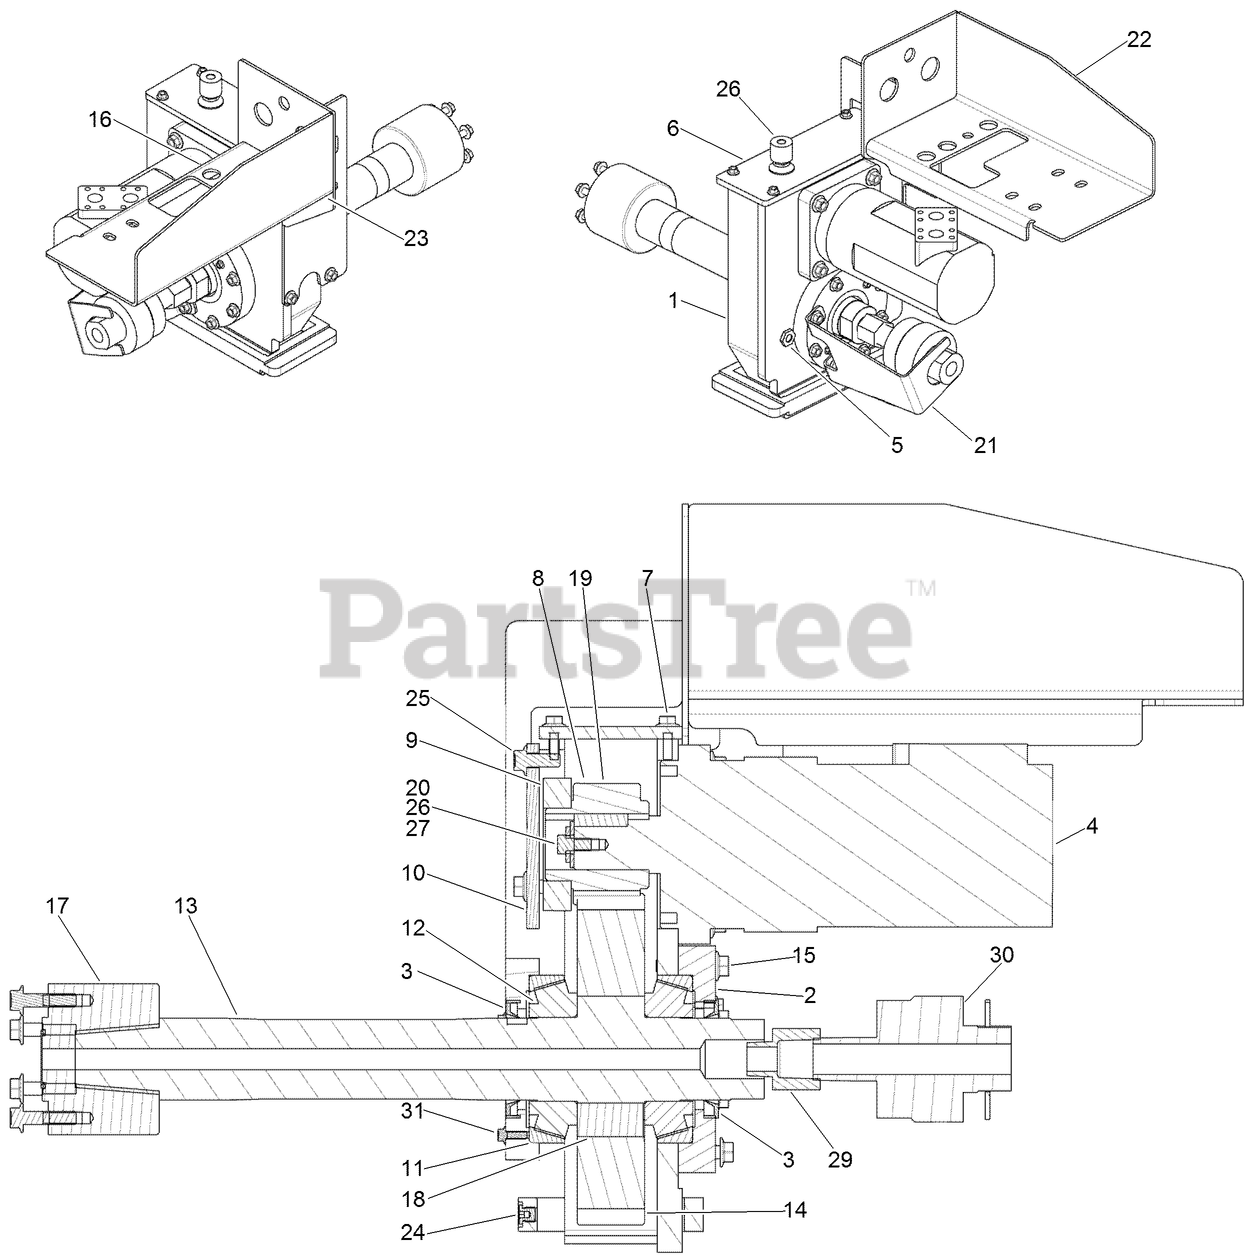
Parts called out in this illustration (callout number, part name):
1	BOX-ROTARY
2	PLATE-BEARING CAP
3	SEAL-SHAFT
4	HYD MOTOR ASM
5	PLUG-SITE, GLASS
6	ASSEMBLY - Top Plate
7	SCREW-HH
8	GEAR-PINION, ROTARY BOX (13T)
9	BEARING-RADIAL BALL
10	PLATE-RETAINING, ROTARY BOX
11	CUP-BEARING
12	CONE-BEARING
13	SPINDLE-ROTARY
14	GEAR-RING, ROTARY BOX (38T)
15	SCREW, METRIC FLANGE w/BODY - M10 x 45
17	ADAPTER - Spindle
18	KEY-ROTARY BOX
19	KEY-BOX, ROTARY
20	WASHER - .562 x 1.375 x .109 in CST ZND
21	BRACKET - Mud Swivel
22	MOUNT - Hose Carrier, Rotary
23	SCREW, METRIC FLANGE w/BODY - M10 x 20
24	PLUG-SOC HD
25	SCREW-FLANGE
26	BREATHER
27	WASHER-FLAT
29	ADAPTER - 1 NPT Fem to 3/4 NPT Male
30	SWIVEL - Rotary
31	SCREW, METRIC FLANGE w/BODY - M6 x 16
